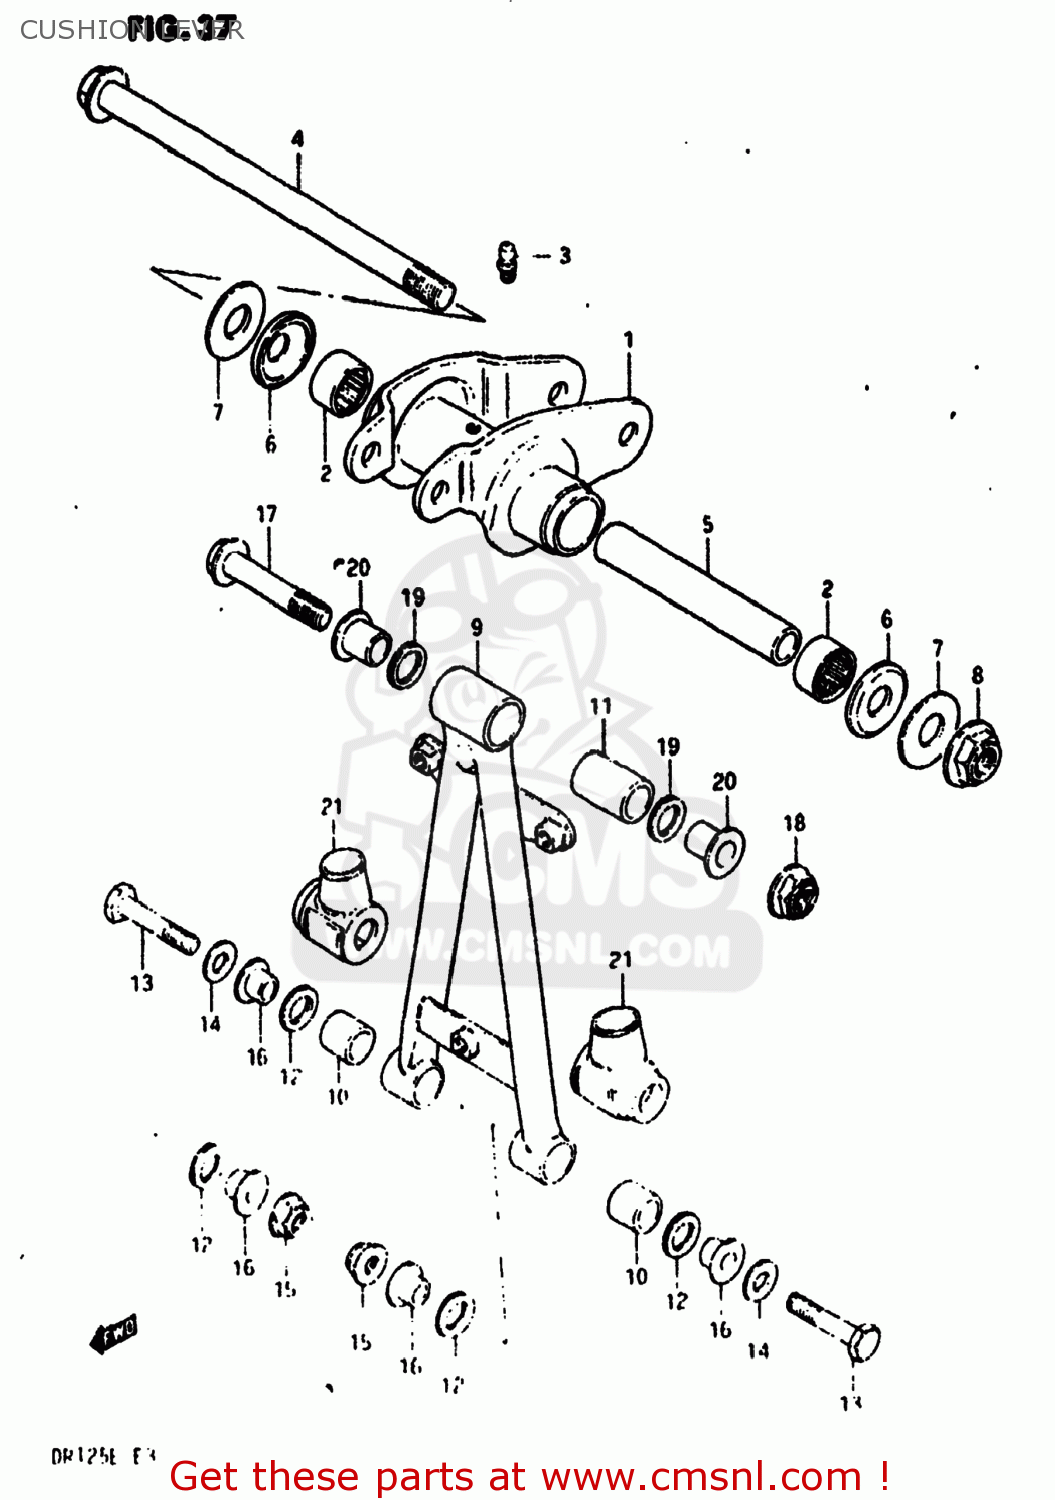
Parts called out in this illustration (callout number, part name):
1	LEVER ASSEMBLY,REAR CUSHION
2	BEARING(17X25X20)
3	GREASE NIPPLE
4	SHAFT,REAR CUSHION LEVER
5	SPACER,REAR CUSHION LEVER
6	DUST SEAL,REAR CUSHION,LEFT
7	WASHER
8	NUT 12MM
9	ROD SET,REAR CUSHION LEVER
10	BUSHING
11	BUSH,UPPER
12	DUST SEAL,RR CUSHION LOD LWR
13	BOLT,REAR CUSHION ROD
14	WASHER
15	NUT
16	SPACER,RR CUSHION ROD LWR
17	BOLT(10X65)
18	NUT
19	DUST SEAL,LEVER CUSHION UNIT
20	SPACER,RR CUSHION ROD UPR
21	BOOT,REAR CUSHION ROD,LOWER
